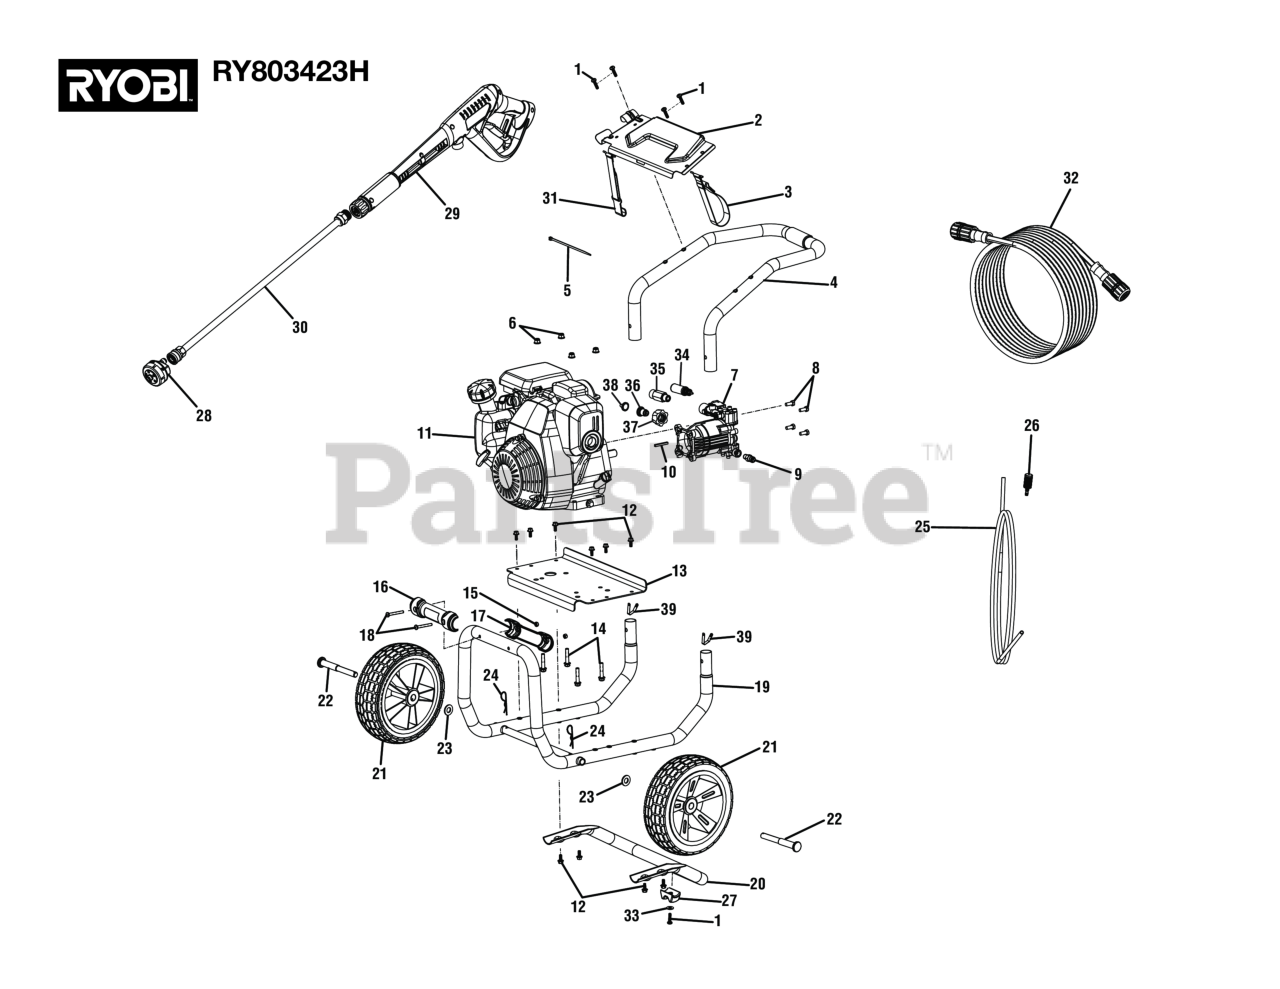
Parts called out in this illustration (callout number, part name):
1	Screw (M6 x 1.25in., T30 Torx Pan Hd.)
2	Performance Panel
3	Hose Holder Strap
4	Handle Assembly
5	Cable Tie
6	Lock Nut (M8 x 1.25 mm, Flange)
8	Bolt (5/16-24 x 3/4 in., Hex Hd.)
9	Thermal Release Valve.
10	Output Shaft Key (3/16 in. x 40 mm)
11	Engine
12	Flange Bolt (M6 x 1 x 16 mm, Hex Hd.)
13	ENGINE PLATE
14	Bolt (M8 x 1.25 x 40 mm, Flange Hd.)
15	Lock Nut (M6 x 1)
16	Handle Grip (Front)
17	Handle Grip (Back)
18	Screw (M6 x 1 x 48 mm, T30 Torx Pan Hd.)
19	Main Frame Assembly
20	Rear Frame Assembly
23	Washer (1/2 in.)
24	Hitch Pin
25	Detergent Injection Tube
26	Detergent Injection Filter
27	Rubber Foot
28	5-in-1 Nozzle
29	Trigger Handle (Inc. Key Nos. 61-64)
30	Extension Wand
31	Surface Cleaner Hanger Adjustable Strap
32	High Pressure Hose
33	Washer (1/4 in.)
34	Unloader Valve Assembly
35	Outlet Tube
36	Inlet Filter Connector
37	Inlet Filter Adapter/Brass Insert
38	Filter Screen (Pump Inlet)
39	Lock Button w/Spring Clip.
